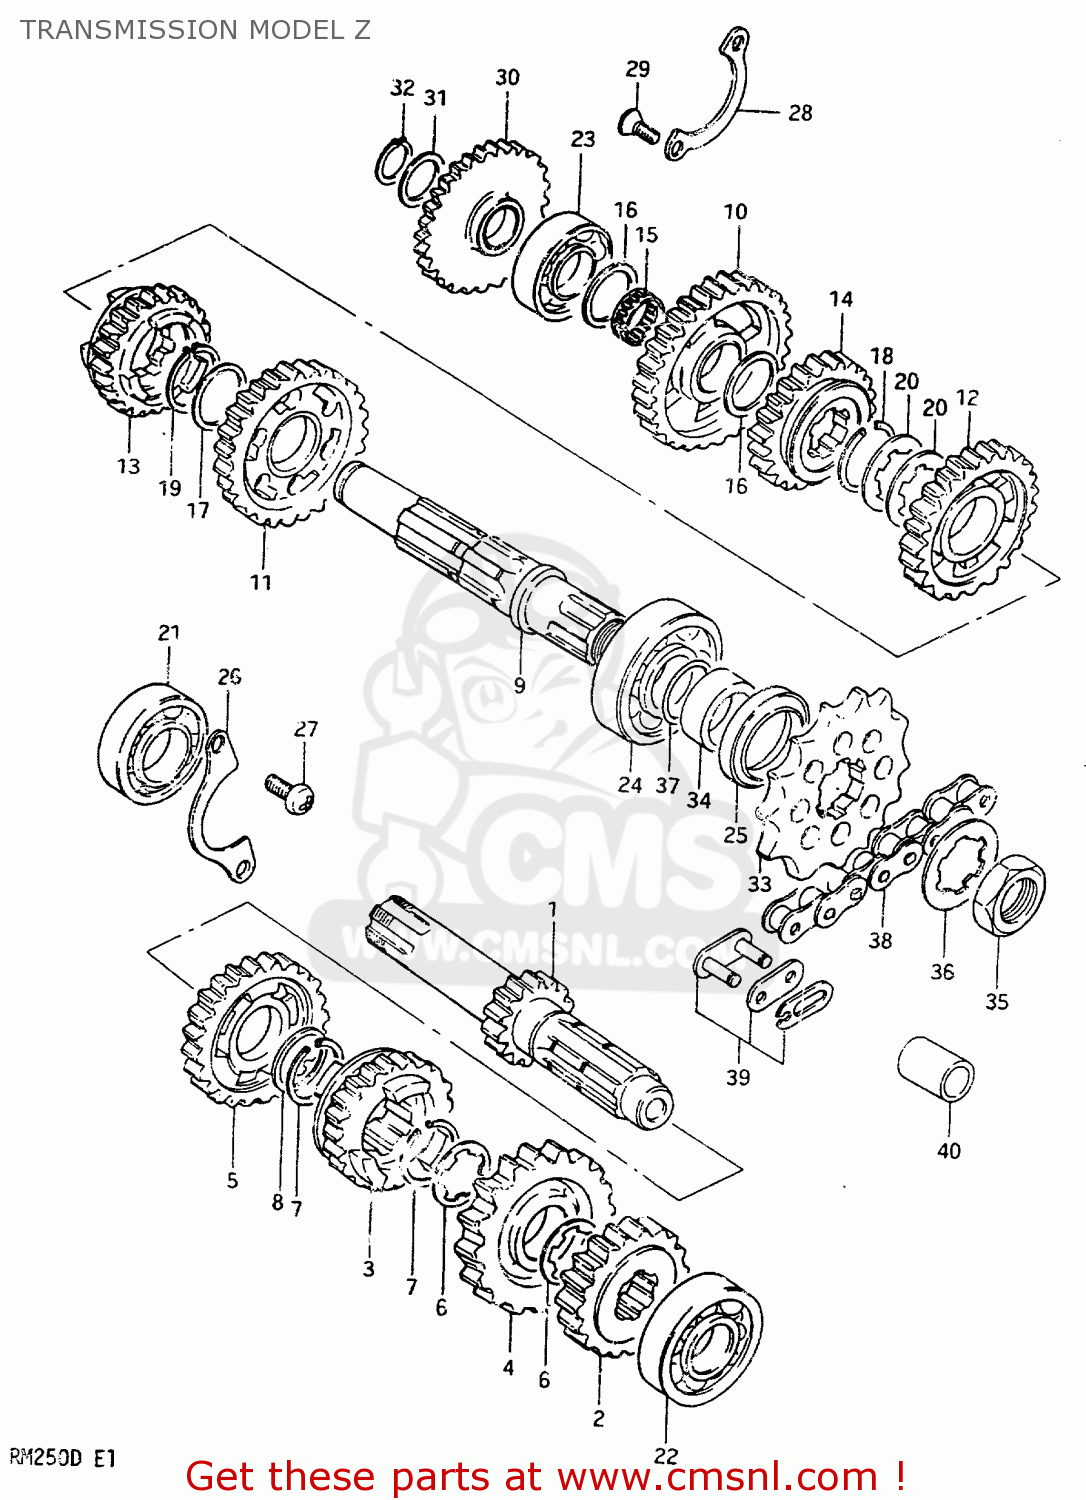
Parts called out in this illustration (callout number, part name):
1	SHAFT,COUNTER
2	GEAR,SECOND DRIVE
3	GEAR,THIRD DRIVE
4	GEAR,FOURTH DRIVE
5	GEAR,FIFTH DRIVE
6	WASHER,LOCK
7	CIRCLIP
8	SHIM(22X28X0.5)
9	SHAFT,DRIVE
10	GEAR,1ST DRIVEN(NT:27)
11	GEAR,SECOND DRIVEN
12	GEAR,THIRD DRIVEN
13	GEAR,FOURTH DRIVEN
14	GEAR,FIFTH DRIVEN
15	BEARING(17X21X9.8)
16	WASHER
17	SHIM
18	CIRCLIP
19	CIRCLIP
20	WASHER,LOCK
21	BEARING(20X52X15)
22	BEARING(17X40X12)
23	BEARING(17X40X12)
24	BEARING
25	SEAL,OIL(32X42X6)
26	PLATE,COUNTERSHAFT BEARING
27	SCREW 6X12
28	PLATE,DRIVESHAFT BEARING
29	SCREW
30	GEAR,KICK STARTER IDLE
31	WASHER
32	CIRCLIP
33	SPROCKET,ENGINE
34	SPACER(22X32X9.5)
35	NUT
36	WASHER,LOCK
37	O RING(D:1.7,ID:22)
38	CHAIN ASSEMBLY,DRIVE
39	JOINT ASSEMBLY,CHAIN
40	SPACER(12X20X15.3)
